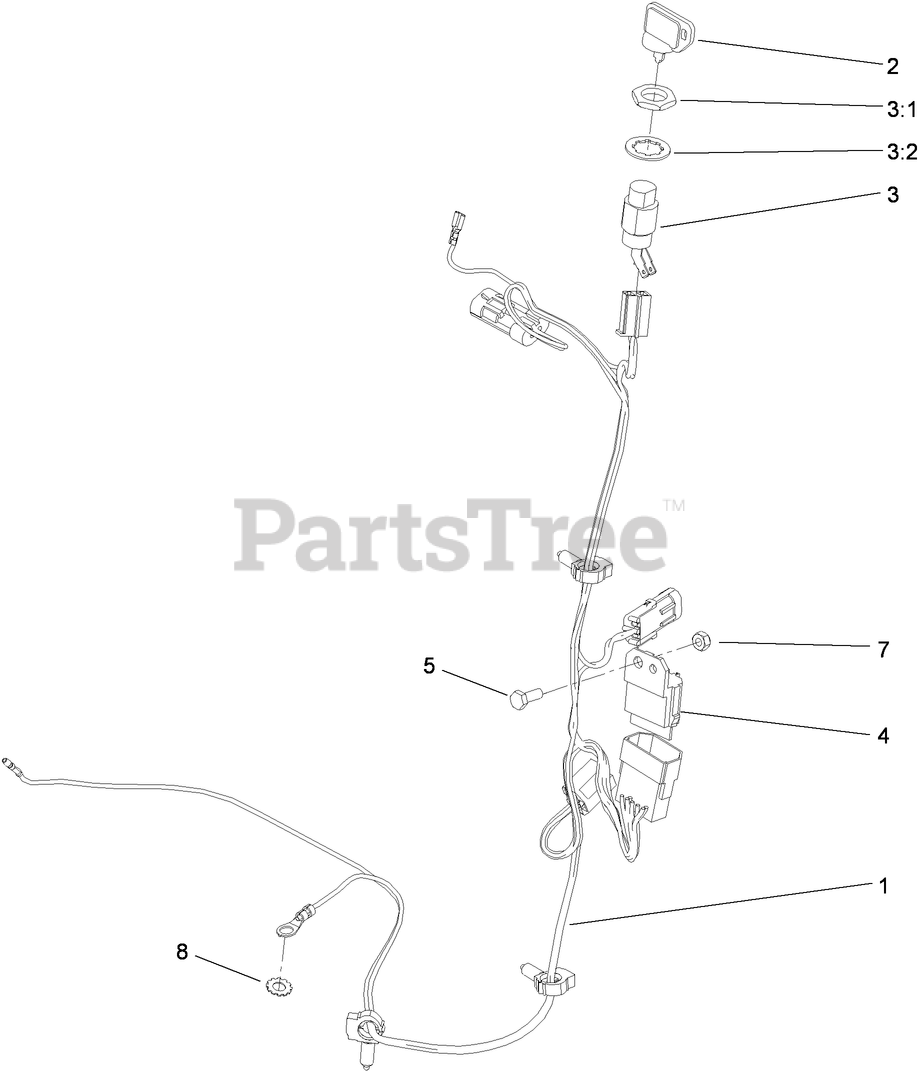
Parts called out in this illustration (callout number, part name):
1	HARNESS-WIRE
2	KEY-IGNITION
3	SWITCH-ON / OFF
3:1	NUT-HH
3:2	WASHER-TOOTH, INTERNAL
4	MODULE-INTERLOCK
7	NUT-LOCK, NI
8	WASHER-LOCK
